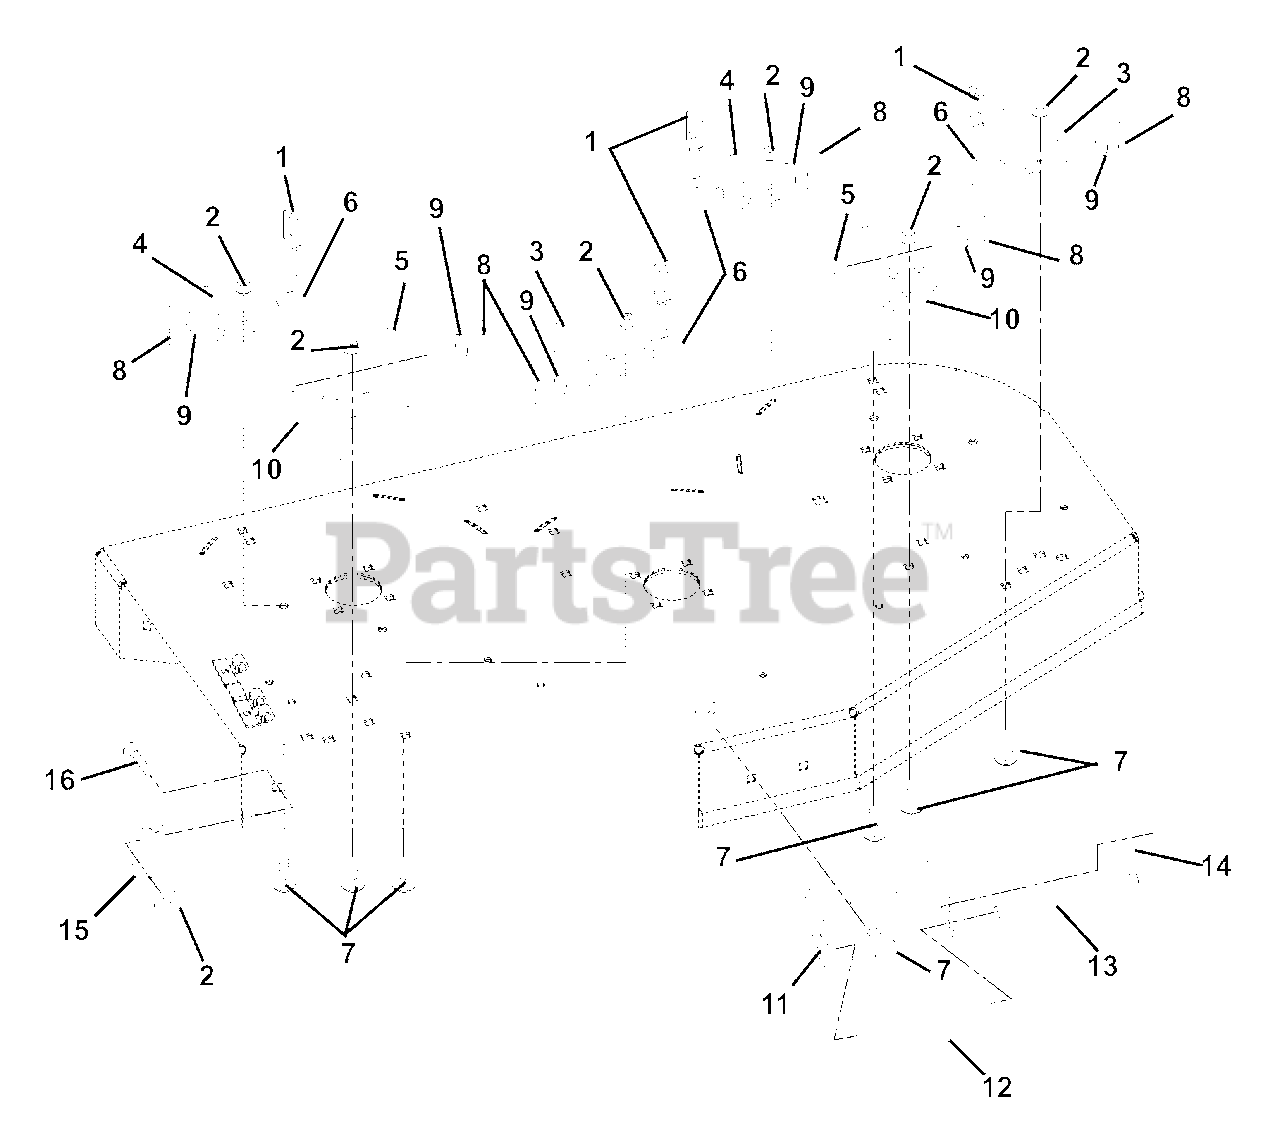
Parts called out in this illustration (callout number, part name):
1	DECK LINK
2	@NUT-LK-NYL-FLG .38-16 YWZC
3	BRACKET, MOUNT,FRONT
4	BRACKET, REAR MOUNT
5	BRACKET, STABILIZER
6	TRUNNION-.50
7	@BLT-RDHDSQNK .38-16X1.00 G5YZ
8	PIN, HAIR, EXT - #16 YWZC
9	WSHR-FL-STL.511X1.441X.125 YWZ
10	ROD,DRAG LINK
11	BRACKET, ROLLER MOUNT
13	PIN, ROLLER
14	PIN, SPRING CLIP
15	BRACKET, CHUTE LOCK
16	@BLT-RDHDSQNK .38-16X1.25 G5YZ
